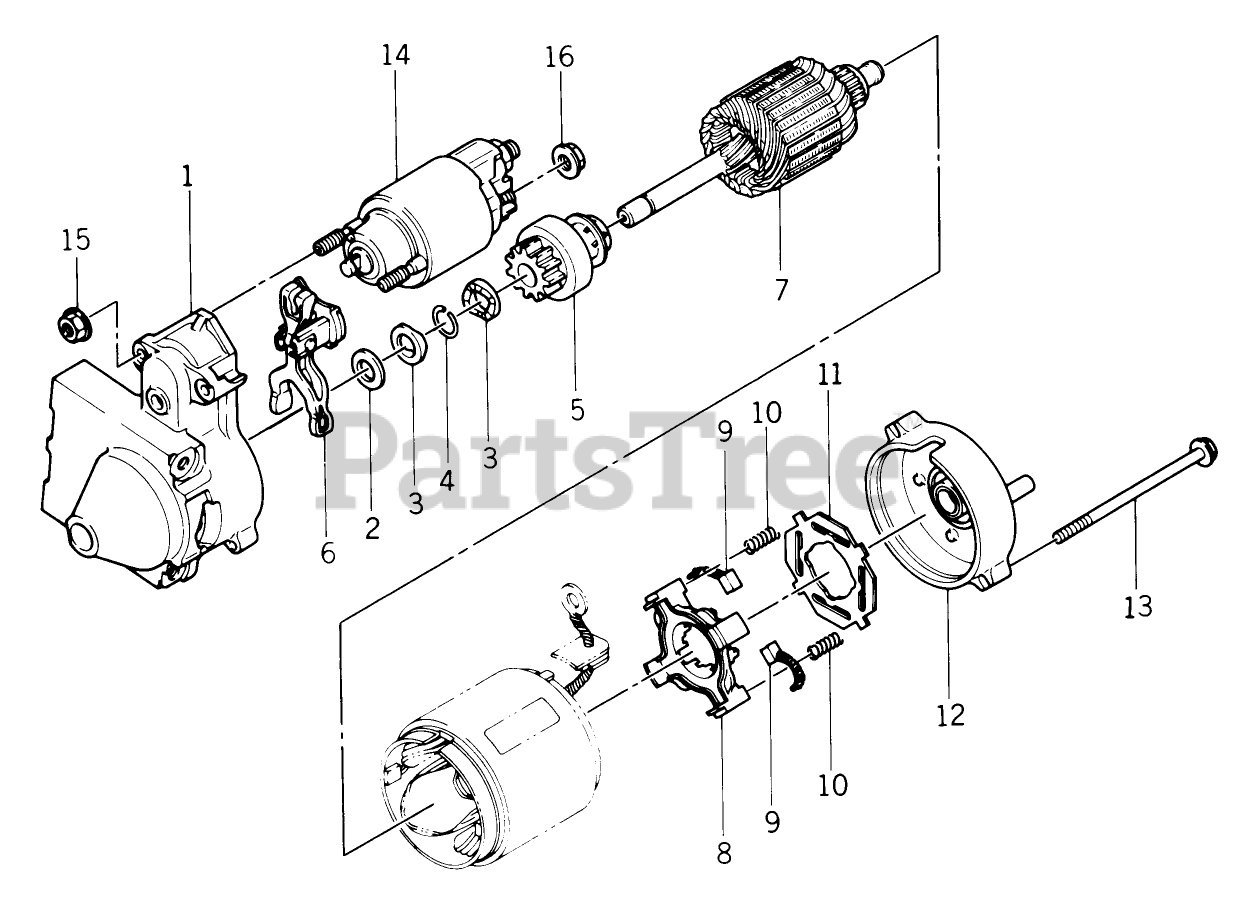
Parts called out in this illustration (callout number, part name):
1	COVER ASS'Y
1	ASS'Y-STARTER COVER
2	RING-SNAP
3	STOPPER PINION
4	CLUTCH ASS'Y
4	ASS'Y-STARTER CLUTCH
5	LEVER SHIFT
5	ASS'Y-SHIFT LEVER
6	SWITCH ASS'Y
6	ASS'Y-STARTER SWITCH
8	ARMATURE
9	COVER ASS'Y
10	BRUSH HOLDER ASS'Y
11	BRUSH
12	Spring
13	BRUSH
14	SCREW
16	SPRING
17	STOPPER
18	COVER
21	Washer
